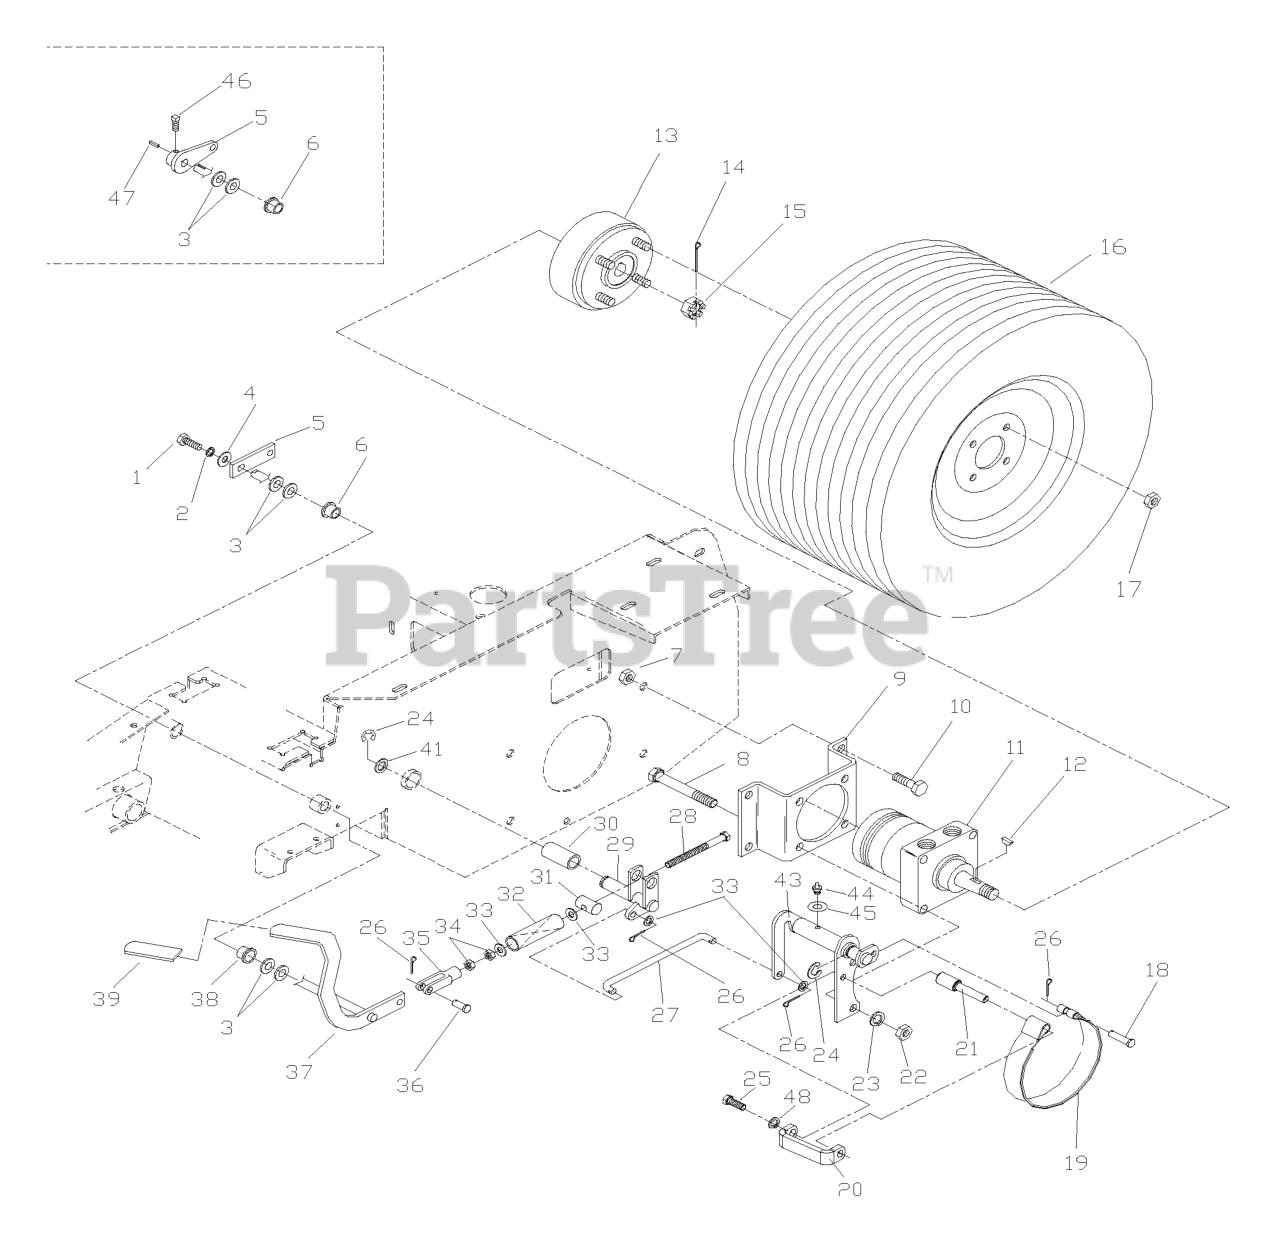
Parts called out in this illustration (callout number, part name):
1	HCS 1/4C X 3/4 HCS
2	LOCKWASHER 1/4"
3	WASHER, 7/16 DISC SPRING
4	WASHER 1/4 FLAT
5	ARM, PARK BRAKE
5	BRAKE ARM WELDMENT
7	NUT 1/2-13 HEX NYLOC ZD
8	HCS 1/2C X 2 3/4
9	MOTOR STANDOFF - PAINTED
10	HCS 1/2C X 1 1/4 SERRATED HEAD
11	MB WHEEL MOTOR
12	WOODRUFF KEY
13	HUB W/BRAKE DRUM
14	COTTER PIN
15	CASTLE-NUT
16	WHEEL/TIRE.ASM.24X12-12.SILVER
16	REAR TIRE/WHEEL ASM
16	TIRE.24X12-12.TURF.MASTER
16	12"RIM 2.5" NEG OFFSET 8.5" W
16	RIM 0 OFFSET 8.5" WIDE
16	VALVE STEM TR-412
17	LUG NUT 1/2F
18	CLEVIS PIN, 3/8 X 1 1/2
19	BRAKE BAND
20	BRAKE SUPPORT BRACKET
20	HCS 3/8 X 3 GD.8
21	BRAKE BAND PIVOT
22	NUT HEX 1/2
23	WASHER 1/2" SPLIT LOCK
24	E RING 3/4
25	HEX BOLT 3/8 X 1"
25	NUT 3/8C CENTERBLOCK
26	RP_COTTER PIN 1/8 X 3/4
27	BRAKE LINKAGE, LT.
27	BRAKE LINKAGE, RT.
28	HCS 3/8F X SPECIAL
30	BRONZE BEARING
31	TRUNION PIN
33	WASHER 3/8 SAE FLAT
35	YOKE-3/8-24 PLTD
36	CLEVIS PIN 3/8 X 1 1/8
37	BRAKE LEVER WIDMT
39	GRIP, PARK BRAKE
43	LT.BRAKE WLDMT
43	RT.BRAKE WLDMT
44	ZERK
46	SCREW 5/16C X 5/8 SQ HEAD
48	SLW 3/8 STD
